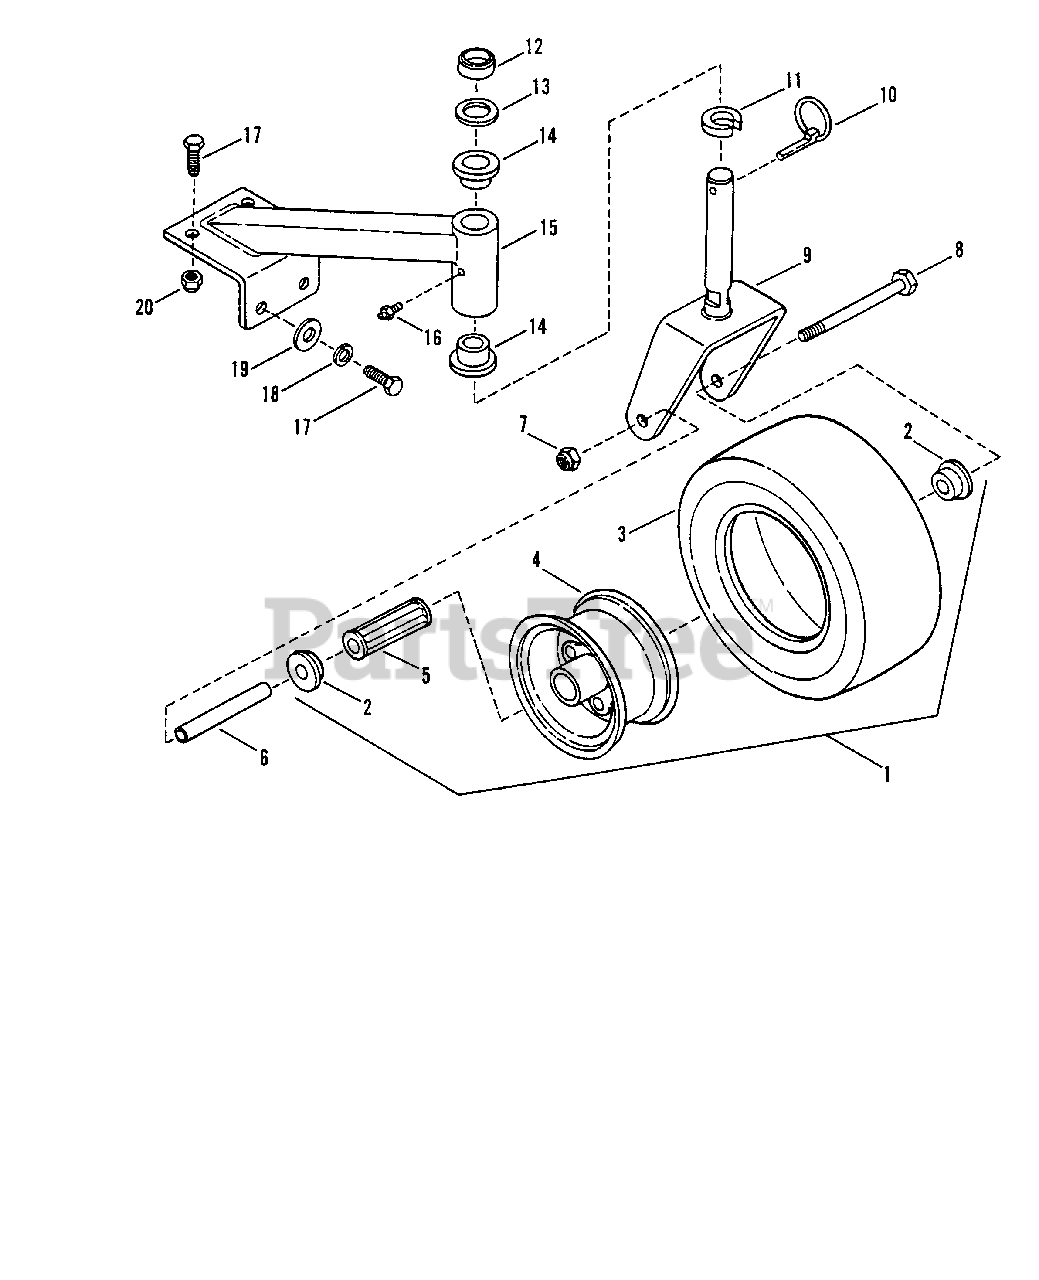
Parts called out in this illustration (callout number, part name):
1	ASSEMBLY, Wheel & Tire
2	RETAINER, Flanged
3	TIRE, 9 x 3.50 - 4
4	ASSEMBLY, Wheel
5	BEARING, Roller
6	SLEEVE, Axle
7	NUT, 1/2-13 HEX NYLON LOCK
8	BOLT, 1/2-13 X 5-1/2" GD5 YZ
9	YOKE, Caster Weldment
10	PIN,Lynch
11	SPACER
13	SPACER
14	BUSHING, Caster
15	ASSEMBLY, Caster Support
16	FITTING, Lube
17	BOLT, 3/8-16 X 1" GD5 CZ
18	WASHER, 3/8" USS
19	WASHER, 3/8" USS
20	NUT, 3/8-16 HEX NYLON LOCK
